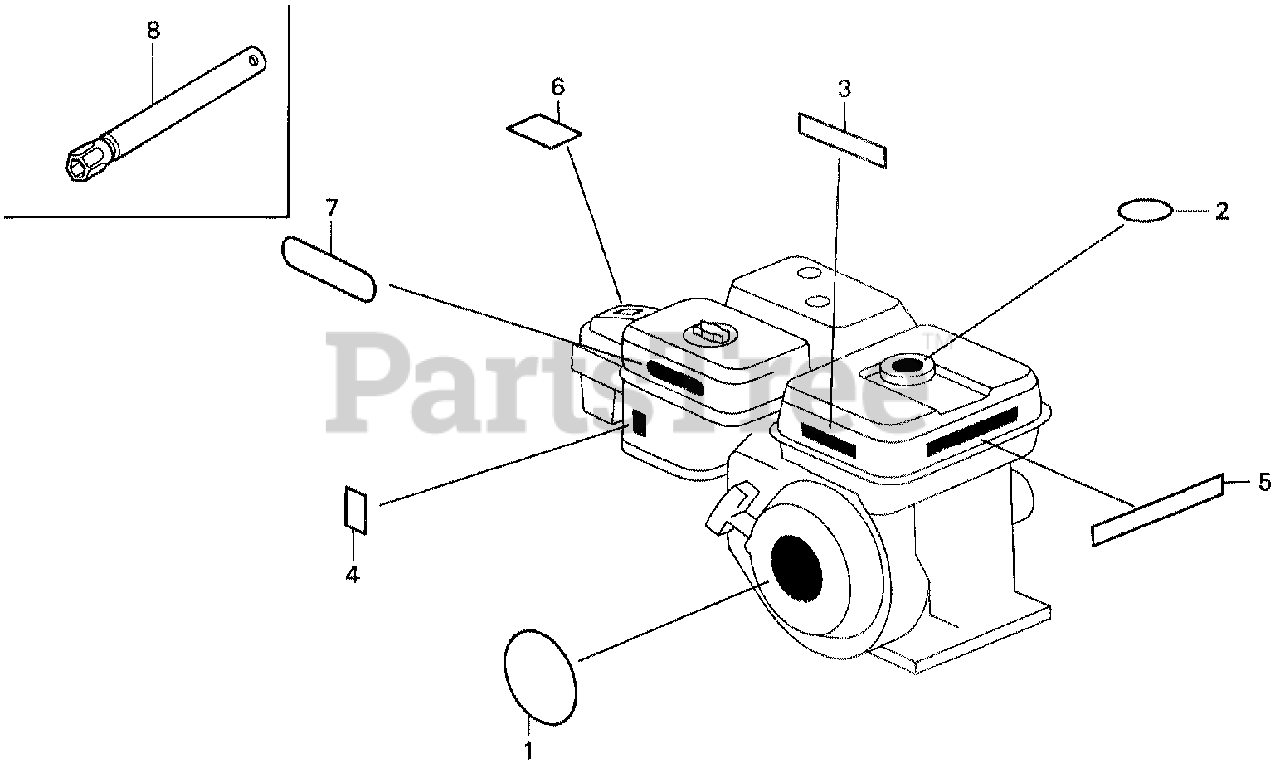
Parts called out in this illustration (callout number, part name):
1	EMBLEM
3	LABEL, CAUTION
4	MARK, CHOKE
5	MARK, OIL ALERT (GERMAN)
5	MARK, OIL ALERT (FRENCH)
5	MARK, OIL ALERT (E)
